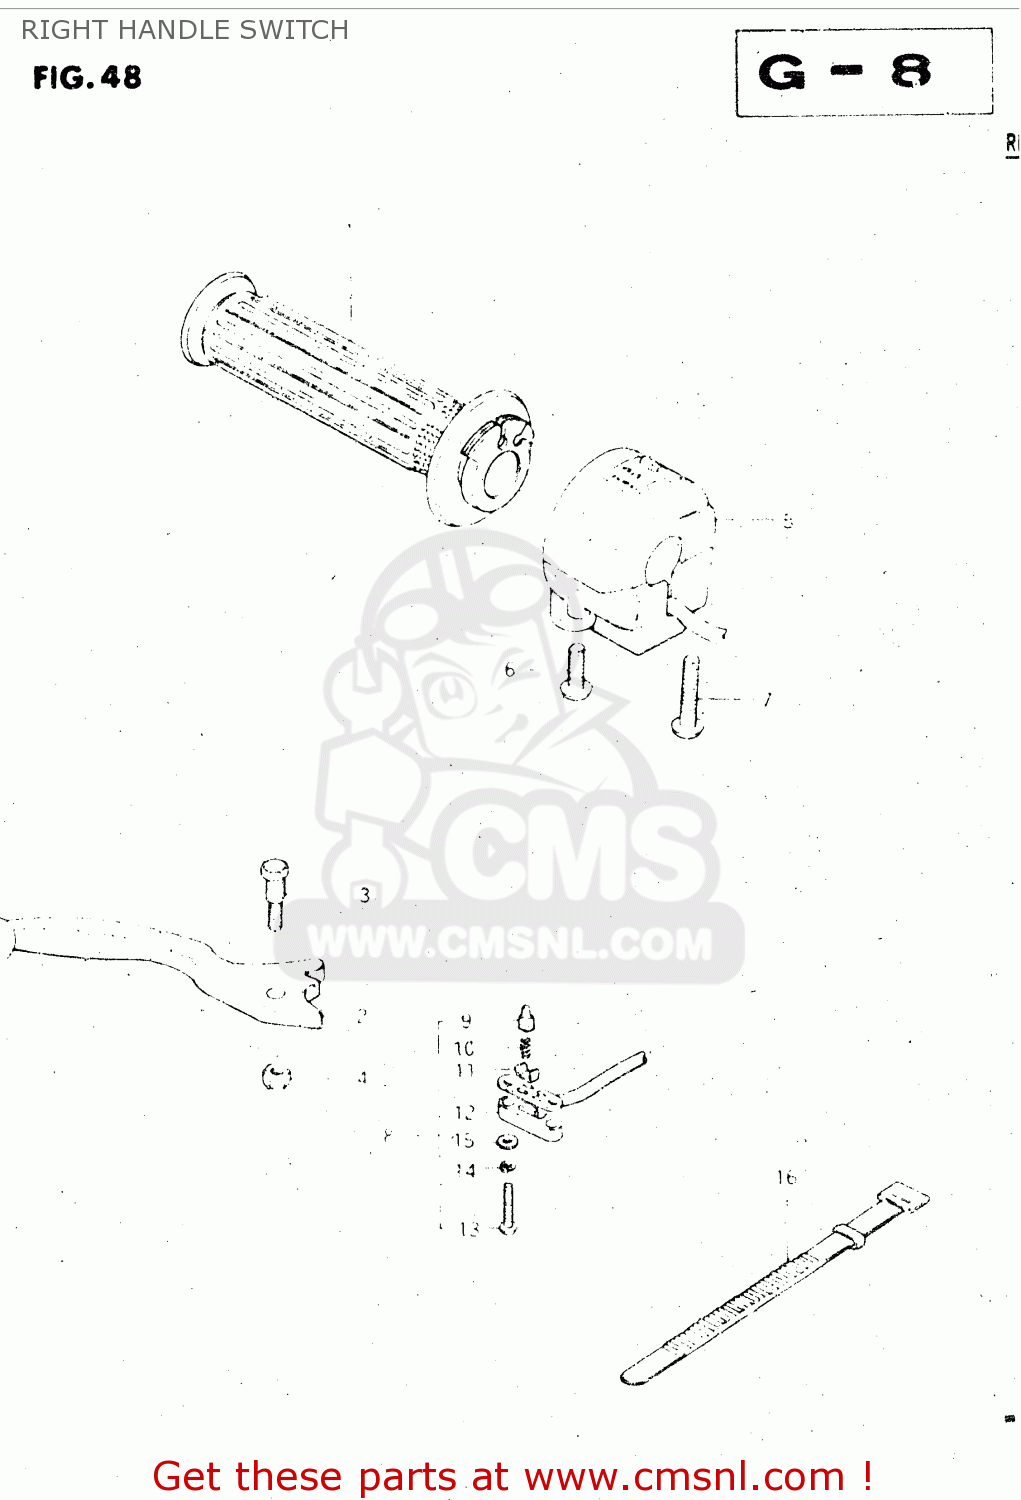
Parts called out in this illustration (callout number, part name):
1	GRIP,THROTTLE
2	LEVER,BRAKE
3	BOLT
4	NUT 6MM
5	SWITCH ASSY, HANDLE RH
6	SCREW
7	SCREW
8	SWITCH ASSEMBLY
9	HOLDER
10	SPRING
11	PLATE
12	COVER,FR BK TERMINAL BASE
13	SCREW
14	LOCK WASHER
15	WASHER
16	CLAMP(L:120)
